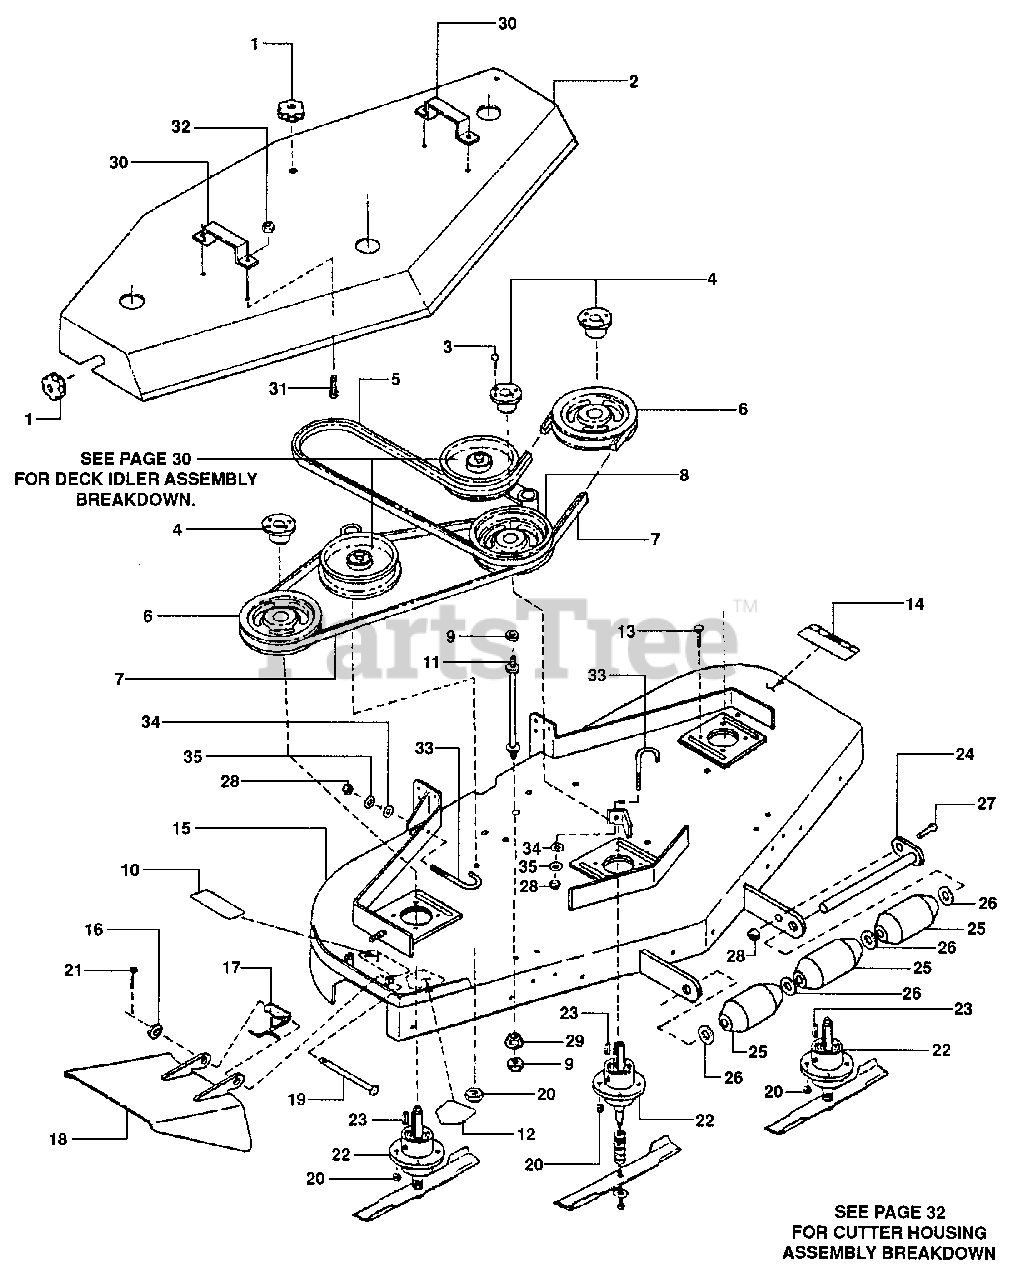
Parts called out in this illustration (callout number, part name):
1	KNOB, Hood
2	HOOD
3	BOLT, 1/4-20 x 7/8" Hex Head Cap
4	BUSHING, Taperlock
5	BELT, Engine To Deck
6	PULLEY, Cutter Blade Drive
7	BELT, Blade
8	PULLEY, Cutter Blade Drive (Double Groove)
9	NUT, 5/16-18 Hex (Nyloc)
10	DECAL, Caution
11	STUD, Hood Mount
12	DECAL, Danger
13	SCREW, 3/8-16 x 1-1/4" Hex Head Cap
14	DECAL, Caution
15	WELDMENT, 52" Deck
16	WASHER, 5/16 Flat
17	SPRING, Chute
18	DEFLECTOR, Chute, 52" Deck
19	ROD, Chute Pivot
20	NUT, 3/8-16 Hex Lock (Nyloc)
21	PIN, 3/32 x 1" Cotter
22	ASSEMBLY, Cutter Housing
23	KEY, Spindle
24	WELDMENT, Roller Pivot Pin
25	ROLLER
26	WASHER, 5/8 Flat
27	BOLT, 3/8- x 1" Hex Head
28	NUT, 3/8- Hex Lock (Nyloc)
29	NUT, 5/16-18 Hex Flange Lock
30	HANDLE
31	SCREW, 1/4- x 3/4" Hex Head Cap
32	NUT, 1/4- Hex Lock (Nyloc)
33	"S" ROD
34	WASHER, 3/8" Flat
35	WASHER, 3/8 Split Lock
